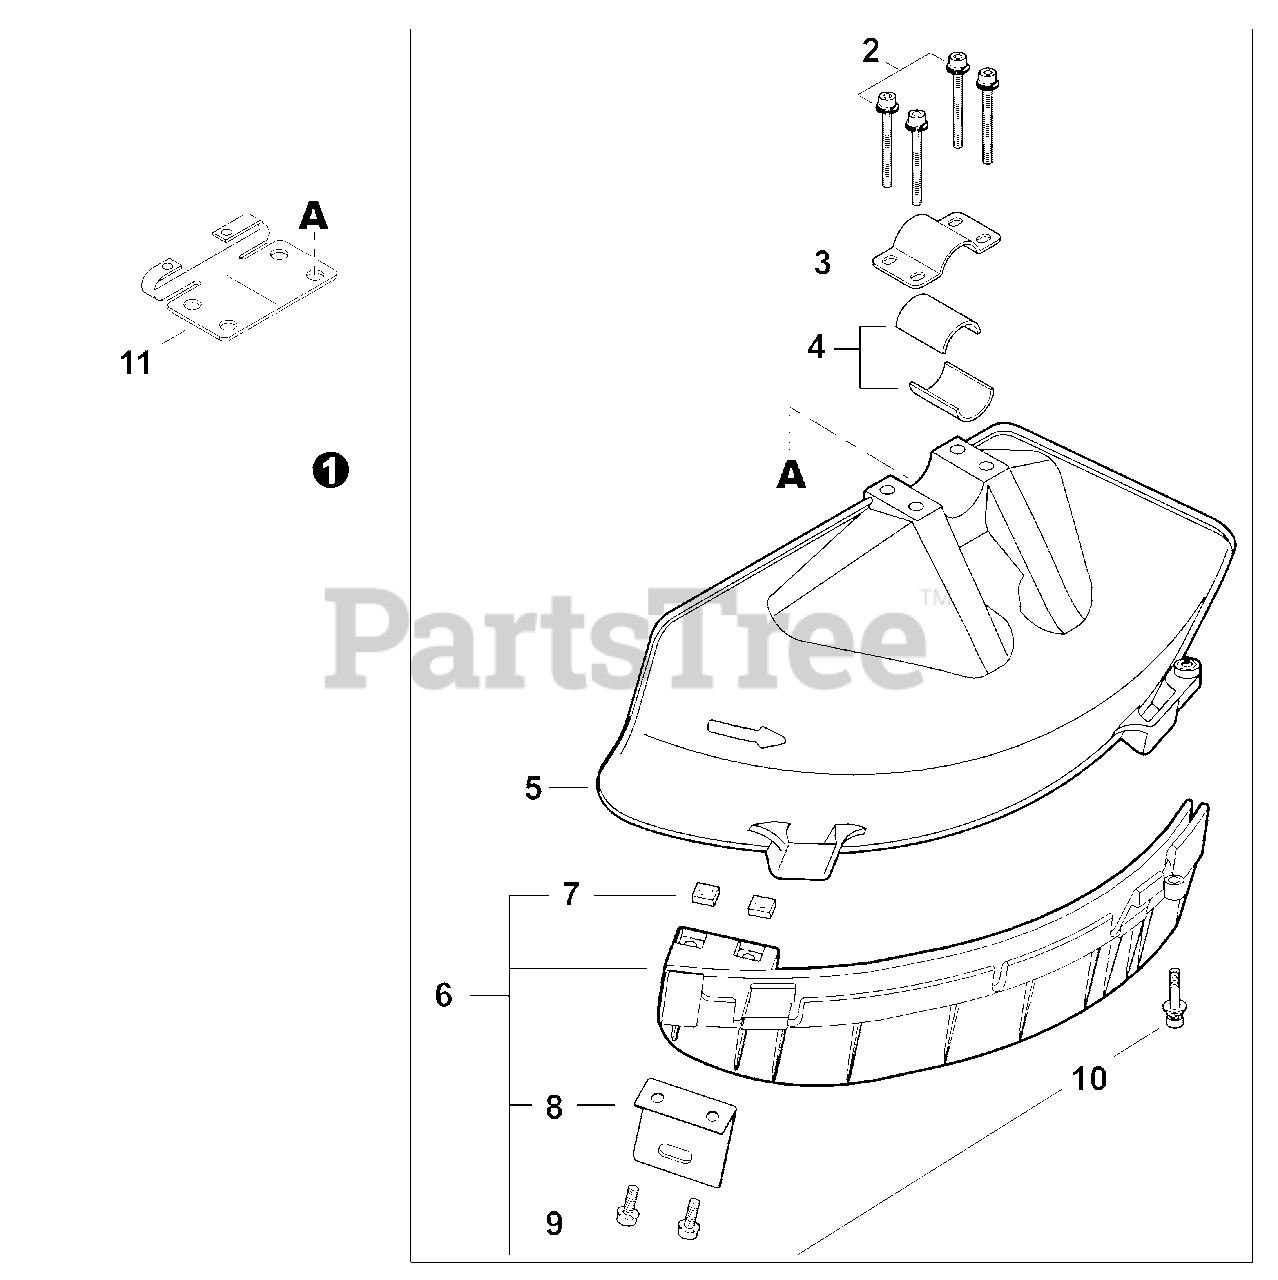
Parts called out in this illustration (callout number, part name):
1	DEBRIS SHIELD KIT
2	BOLT M5×45
3	CLAMP, UPPER
5	SHIELD, DEBRIS - BLADE
6	DEBRIS SHIELD EXTENSION ASSY
9	BOLT 5×16
10	BOLT M5×22
11	BRACKET, SHIELD
